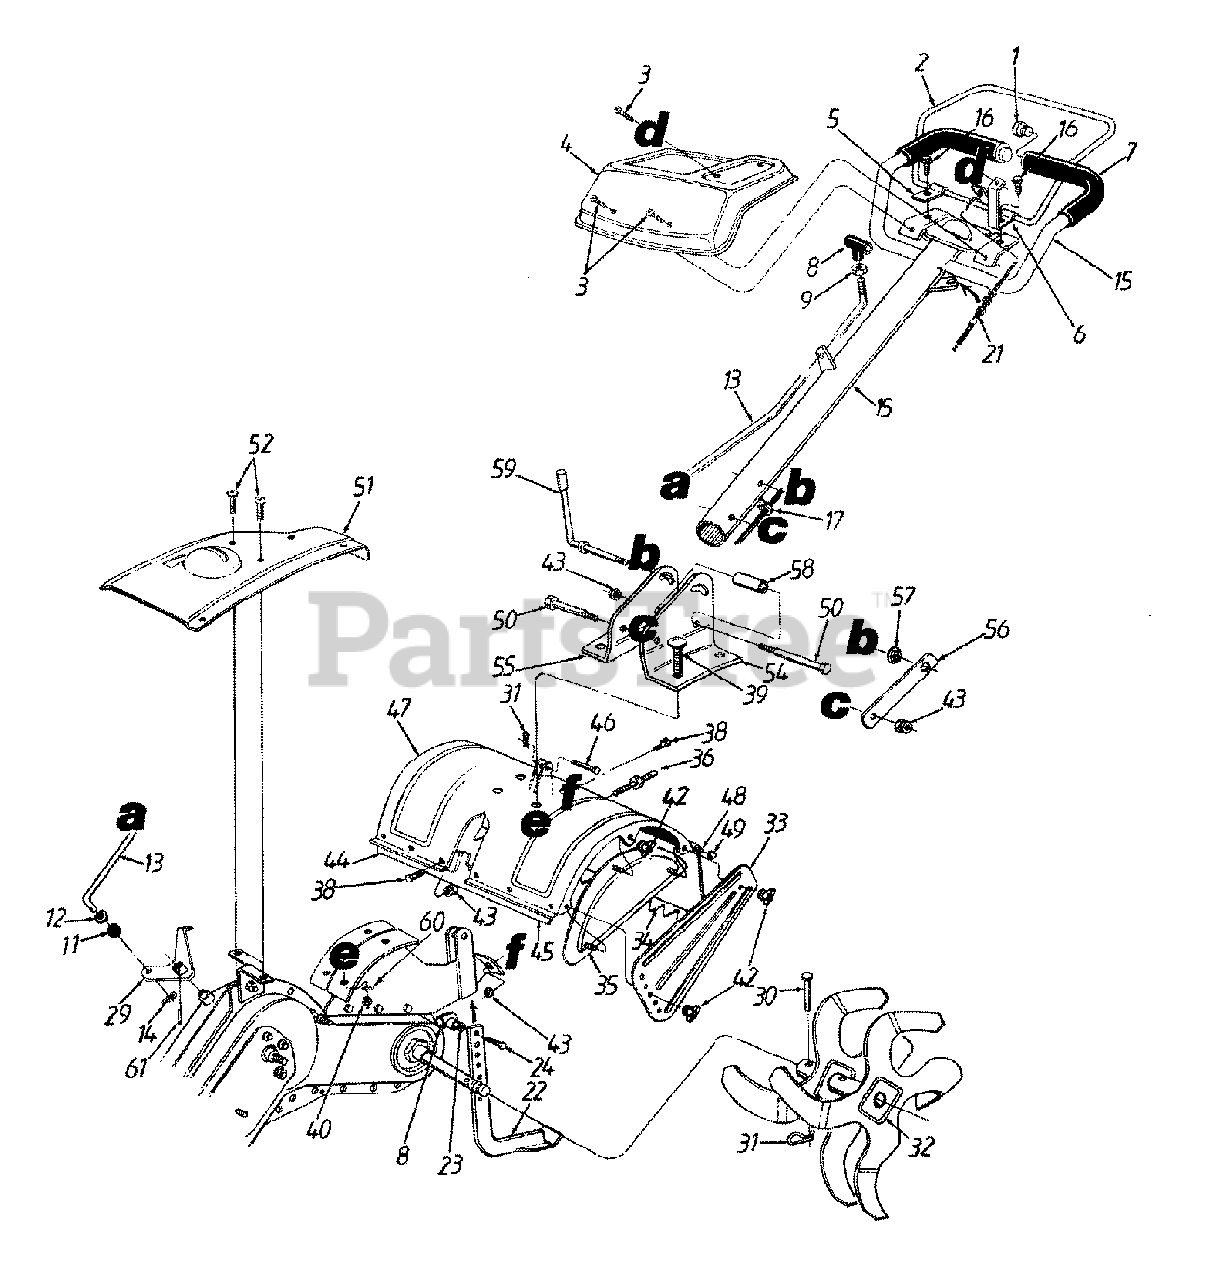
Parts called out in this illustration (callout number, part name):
1	Vinyl End Plug
3	Torx Mach. AB-Tap Scr. 1/4 x .62" Lg.
7	Grip
9	Hex Jam Nut 3/8-16 Thd.
11	Rubber Washer
12	Fl-Wash. .344" I.D. x .6" O.D.
13	Gear Shift Rod
14	Hairpin Clip
16	Hex Wash. Hd. TT-Tap Scr. 1/4-20 x .5" Lg.
21	Clutch Cable
23	Fl-Wash. 3/8" I.D. x 5/8" O.D.
24	Hex Bolt 3/8-16 x 1" Lg.
33	Side Shield
34	Rear Tine Shield
35	End Cover Ass'y.
36	Hex Bolt 5/16-18 x 1" Lg.
38	Hex Bolt 5/16-18 x .75" Lg.
39	Carriage Bolt 3/8-16 x 1" Lg.
40	Hex Nut 3/8-16 Thd.
42	Wing Nut 5/16-18 Thd.
43	Hex Flange Top L-Nut 5/16-18 Thd.
46	Clevis Pin .375" Dia.
48	Tiller Flap Rod
49	Cap Speed Nut
50	Hex Bolt 5/16-18 x 3" Lg.
52	Torx Mach. AB-Tap Scr. 1/4 x .6"
54	Handle Brkt. - L.H.
55	Handle Brkt. - R.H.
56	Hex Nut Retainer Brkt.
57	Hex Flange Nut 3/8-24 Thd.
58	Spacer .322 Dia.
59	Handle Adjustment Crank
60	L-Wash. 3/8" I.D.
61	Spiral Pin 1" Lg.
